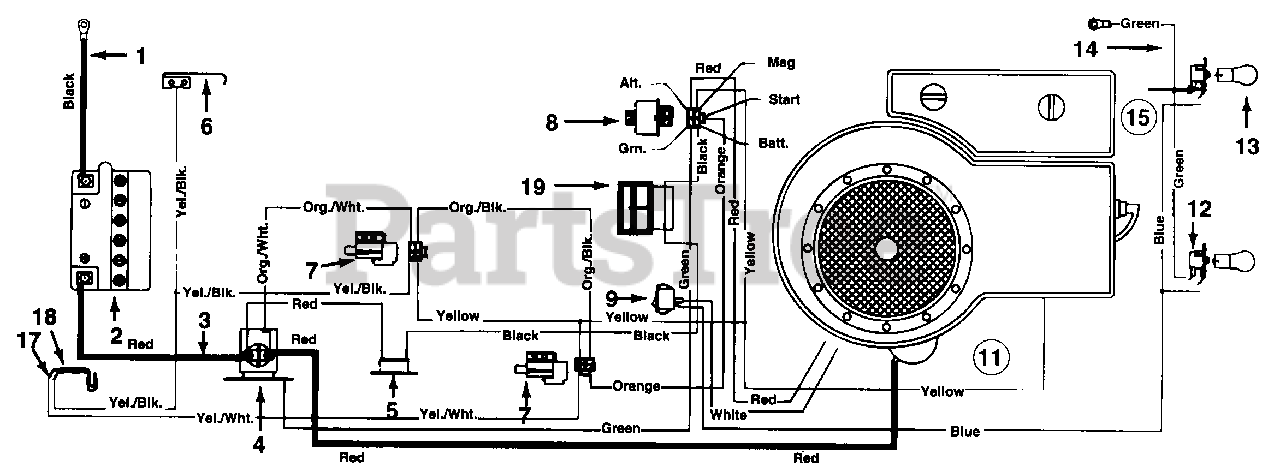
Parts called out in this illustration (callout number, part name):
1	Ground Wire
2	Battery
3	Electric Wire - 8.0" Lg.
4	Solenoid
5	Circuit Breaker
6	Spring Switch (Reverse)
7	Safety Switch
8	Ignition Switch
9	Light Switch
11	Harness
12	Socket (Sq. Headlights)
13	Bulb (Sq. Headlights)
14	Ground Wire
15	Headlight Harness w/Amp & Light Switch
15	Headlight Harness
17	Safety Switch (Seat)
18	Safety Switch (Seat)
19	Ammeter
